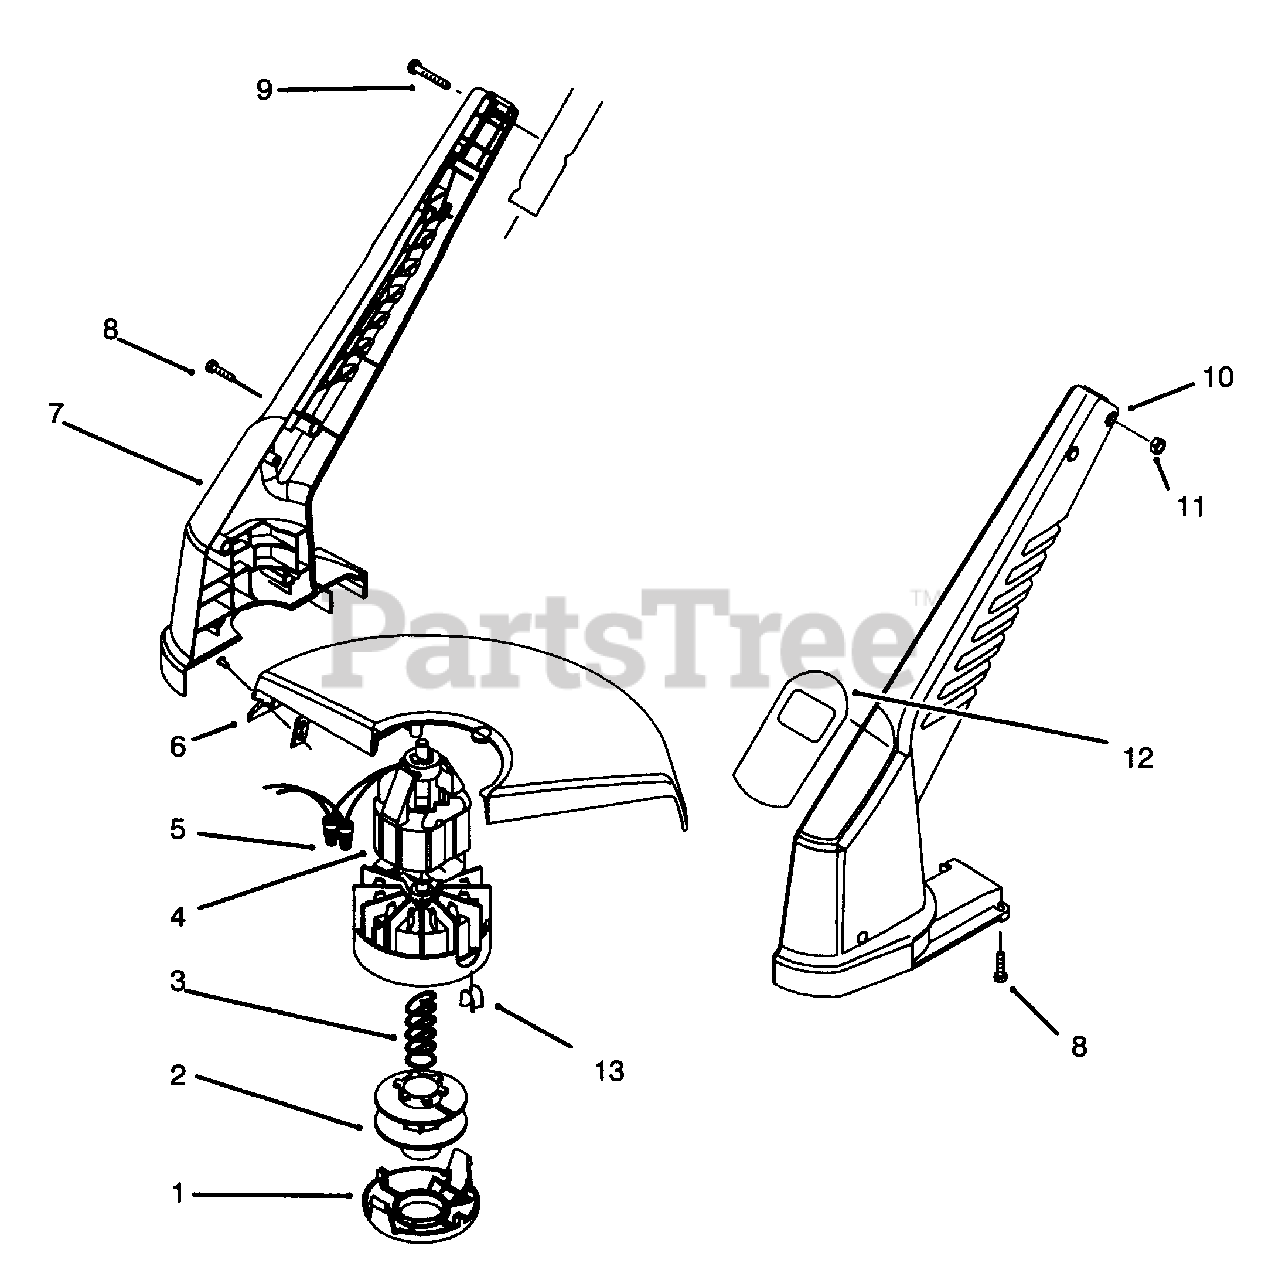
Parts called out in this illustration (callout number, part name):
4	Motor Assembly (Incl. Ref. #13)
5	Connector-Wire Nut
6	Shield-14"
7	Housing R.H.
8	Screw-Pan Hd. Tapping
9	Screw-Pan Hd.
10	Housing L.H.
12	Decal-14" Trimmer
